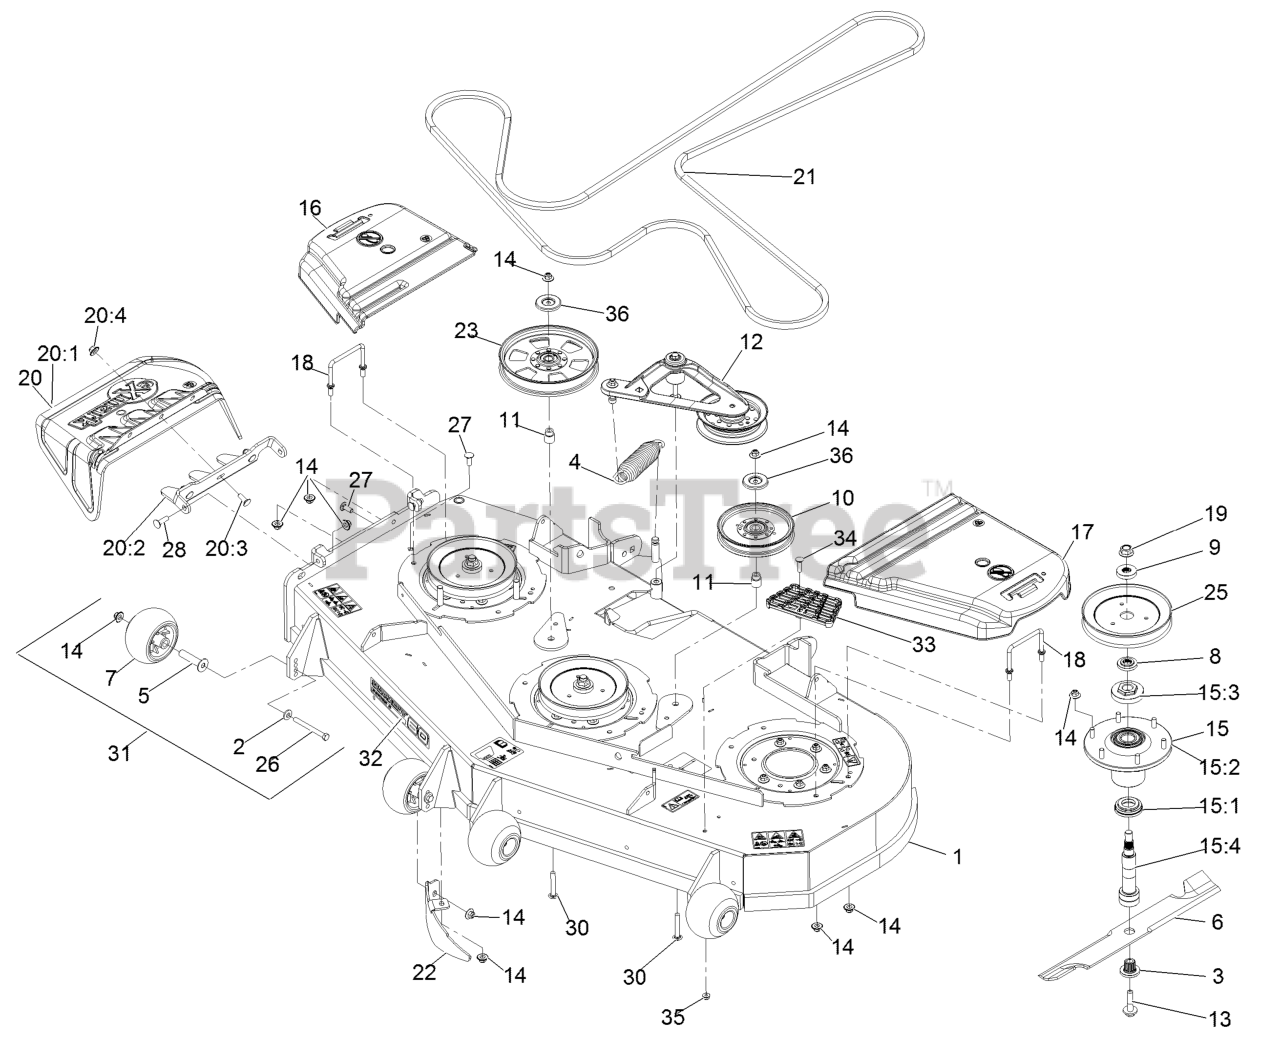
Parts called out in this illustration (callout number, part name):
1	DECK ASM,W/DECALS 60
2	WASHER-BELLEVILLE
3	BUSHING,SPLINED
4	SPRING-EXTENSION
5	AXLE, ROLLER
6	Blade-Extreme 2, 20.50"
7	ROLLER-SCALP, ANTI
8	SPACER,SPLINED STEPPED
9	SPACER,SPLINED
10	IDLER-PULLEY
11	BUSHING-IDLER
12	DECK IDLER ASM
13	SCREW,SEMS 1/2-20 X 2.19
14	Nut-Nyloc 3/8-16 Flg
15	ASM,SPINDLE HOUSING
15:1	GUARD,BOTTOM
15:2	ASM,CUTTER HOUSING
15:3	NUT, SPINDLE 7/8-14
15:4	SPINDLE,DOUBLE SPLINE
16	COVER-BELT, RH
17	COVER-BELT, LH
18	WIREFORM-COVER
19	NUT-FLANGE, CENTERLOCK
20	ASM,DISCHARGE CHUTE
20:1	CHUTE,DISCHARGE
20:2	BRACKET,DISCHARGE CHUTE
20:3	SCREW-CARR
20:4	Nut-Nyloc 3/8-16 Flg
21	BELT,V-5V-198.75
22	DOGLEG - LZ60
23	PULLEY-IDLER, FLAT
25	SHEAVE,BLADE DRIVE 7.25
26	SCREW-HH 3/8-16 X 3 3/4 GR 8
27	SCREW-CARR
28	Bolt-Carriage 3/8-16 X 1 1/4
30	SCREW-CARR
31	KIT, ANTI-SCALP ROLLER
32	DECAL, 606
33	STEP-DECK
34	Bolt-Carriage 5/16-18 X 1 1/4
35	NUT-HF, NI
36	SHIELD-DUST
